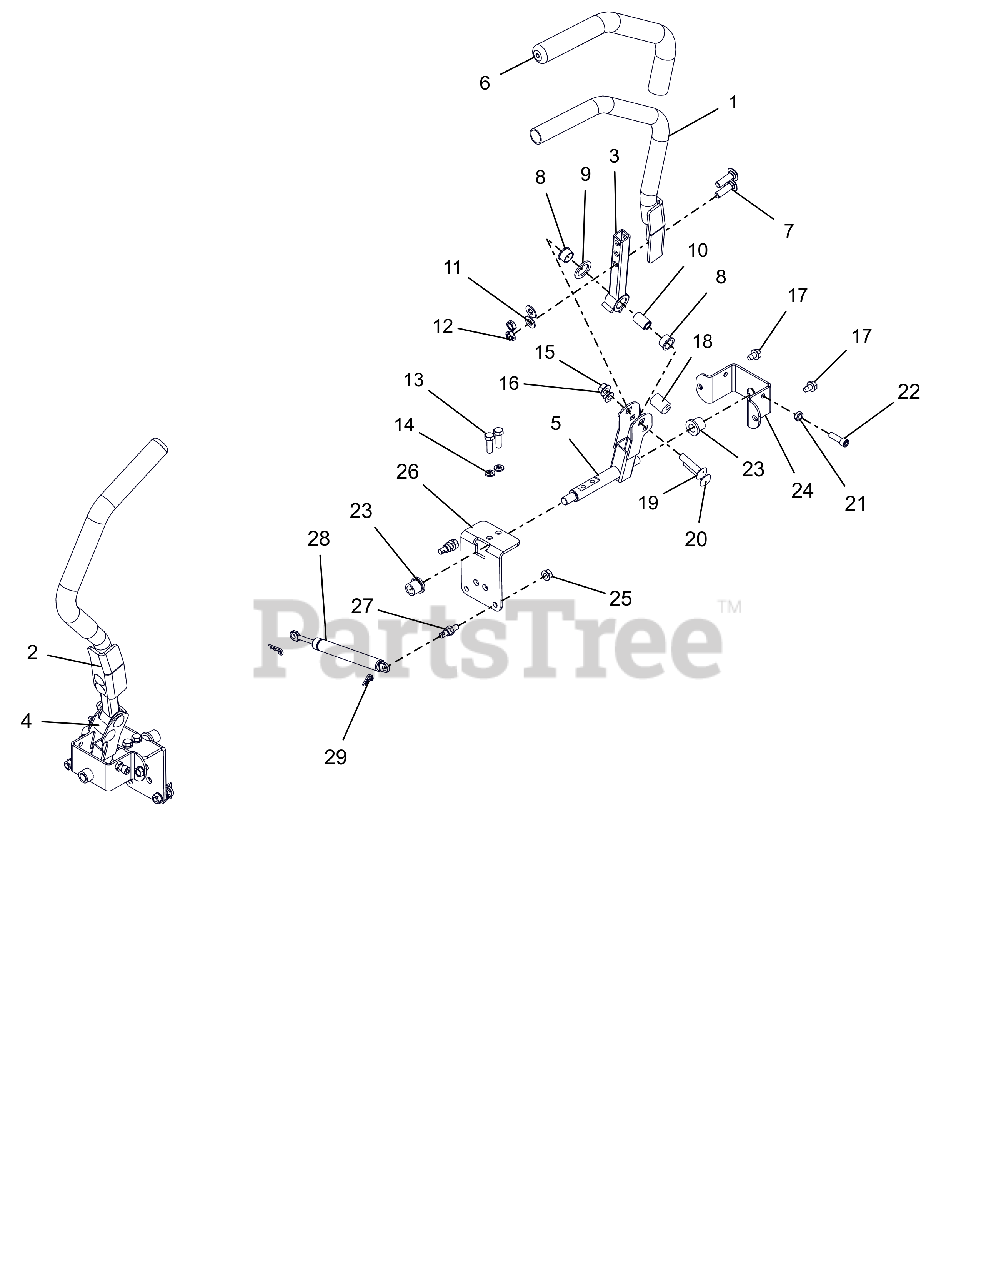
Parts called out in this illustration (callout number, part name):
1	WLDMT, STEERING HANDLE LH
2	WLDMT, STEERING HANDLE RH
3	WLDMT, UPPER CONTROL ARM
4	WLDMT,STEERING ARM LOWER RIGHT
5	WLDMT,STEERING ARM LOWER LEFT
6	GRIP, HANDLEBAR 15" FOAM
7	BLT,RHSSN .38-16X1.25 G5 BFP
8	BSHG-FLG, .625X.75X.450X.875
9	WASHER, FRICTION .875X1.25X.10
10	SPACER, .375X.625X.970 (PM)
11	WSHR,FLT .406X.812X.065 ZCC
12	@NUT-LK-CTR-JAM .375-16 YWZC
13	BLT, HEX .31-18X1.00 G8 ZCC
14	WSHR,LK-REG .312X.078 ZCC
15	NUT-LK-CTR-FLG .375-16 GF ZCC
16	NUT,LK-NYL-FLG .31-18 G5ZC120
17	SCR,TAP .312-18X.50 HWH TR ZCC
18	BSHG,ECCEN .328X.750X1.01 PM
19	BLT,RHSSN .38-16X1.75 G5 BFP
20	BLT,RHSSN .31-18X1.75 G5 BFP
21	NUT-JAM .312-18 G2 ZCC
22	SCR, SKH .312-18X1.00 G8 SS
23	BSHG-FLG .515X.750X.745X1.00NY
24	BRKT, STEERING
25	NUT-LK-TOP-FLG .312-18 GF ZCC
26	BRKT, STEEERING
27	COUPLER, DAMPER MOUNT
28	DAMPER, STRAIGHT MOUNT
29	PIN, HAIR #213 .08X1.19 ZCC
